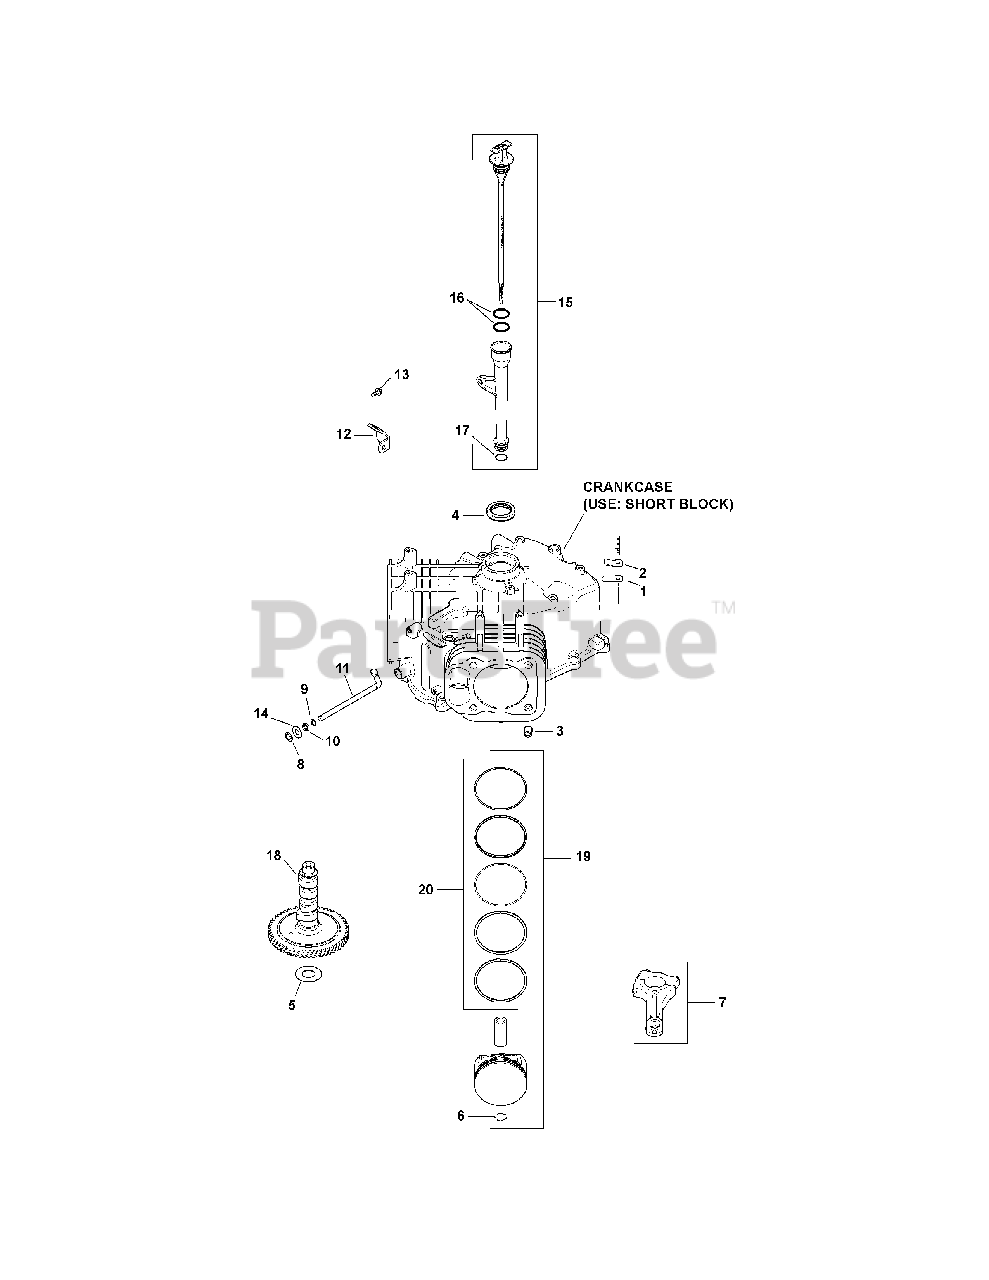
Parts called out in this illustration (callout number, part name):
1	Breather Reed
2	Breather Reed Retainer
4	Oil Seal (Helix Lip)
5	Camshaft Shim (White .028")
5	Camshaft Shim (Blue .03")
5	Camshaft Shim (Red .032")
5	Camshaft Shim (Yellow .034")
5	Camshaft Shim (Green .036")
5	Camshaft Shim (Gray .038")
5	Camshaft Shim (Black .04")
6	Piston Pin Retainer
7	Connecting Rod (Std)
8	Ring Retainer
9	Flat Washer, 11/32
10	Governor Cross Shaft Seal
11	Governor Cross Shaft
12	Oil Fill Tube Bracket
13	Flg. Thd. Frm. Screw, M5 x 0.8 x 13
14	Flat Washer, 9mm
15	Dipstick And Tube Kit
16	Dipstick O-Ring
17	O-Ring, Lower Oil Fill Tube
18	Camshaft Assembly
19	Piston Kit w/ Ring (0.25) 83mm
19	Piston Kit w/ Ring (0.08) 83mm
20	Ring Set, Piston STD
20	Ring Set, Piston (.08)
20	Ring Set, Piston (.25)
